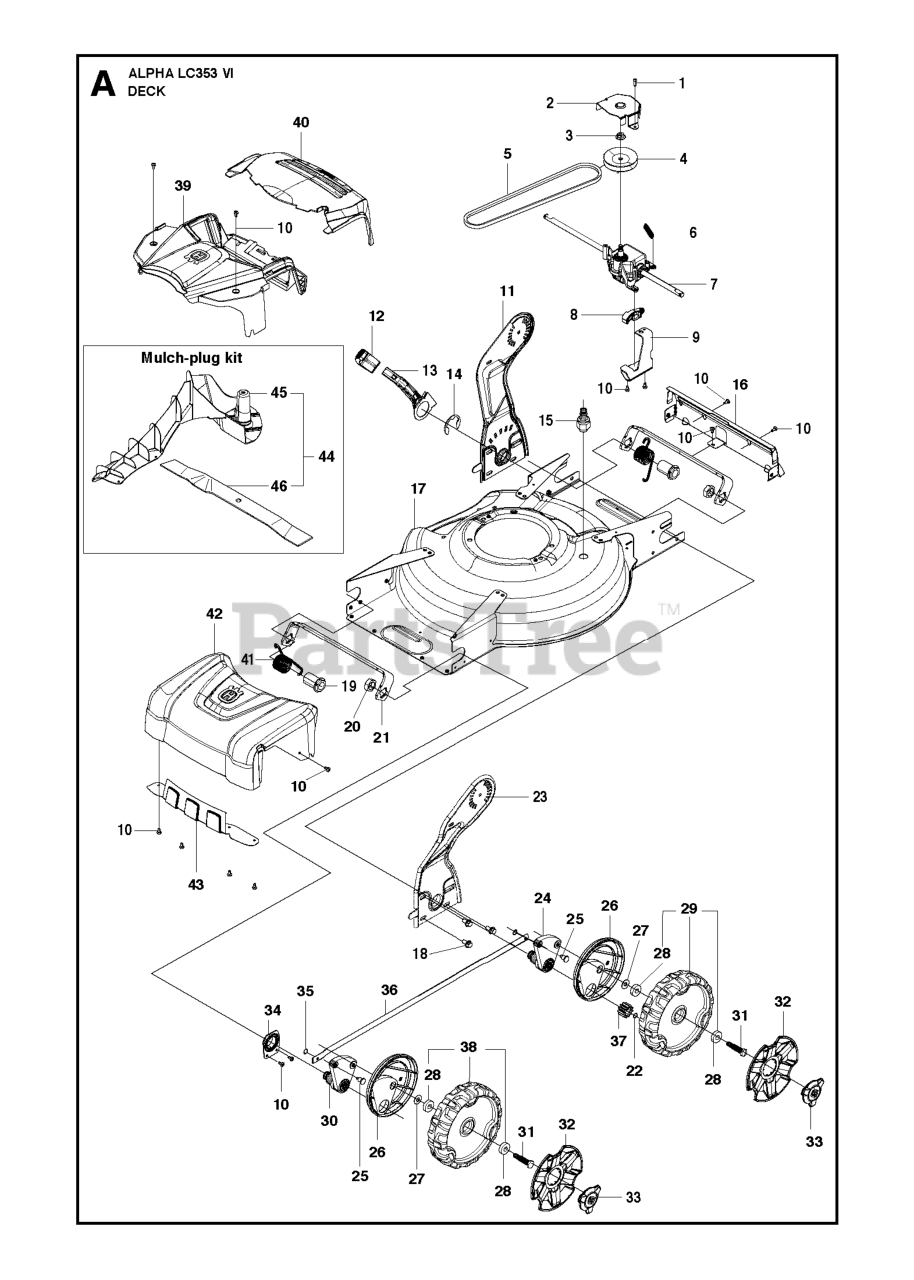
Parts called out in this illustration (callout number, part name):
1	SCREW ITXPANT T50X16 ZN/FE (A
5	BELT WRAPPED V-BELT Z 31 3/4"
10	SCREW ITXPANTT M5X10 ZPB (A00
28	BALL BEARING
35	FASTENER
38	WHEEL ASSY 210, IDLE, MEDIUM
